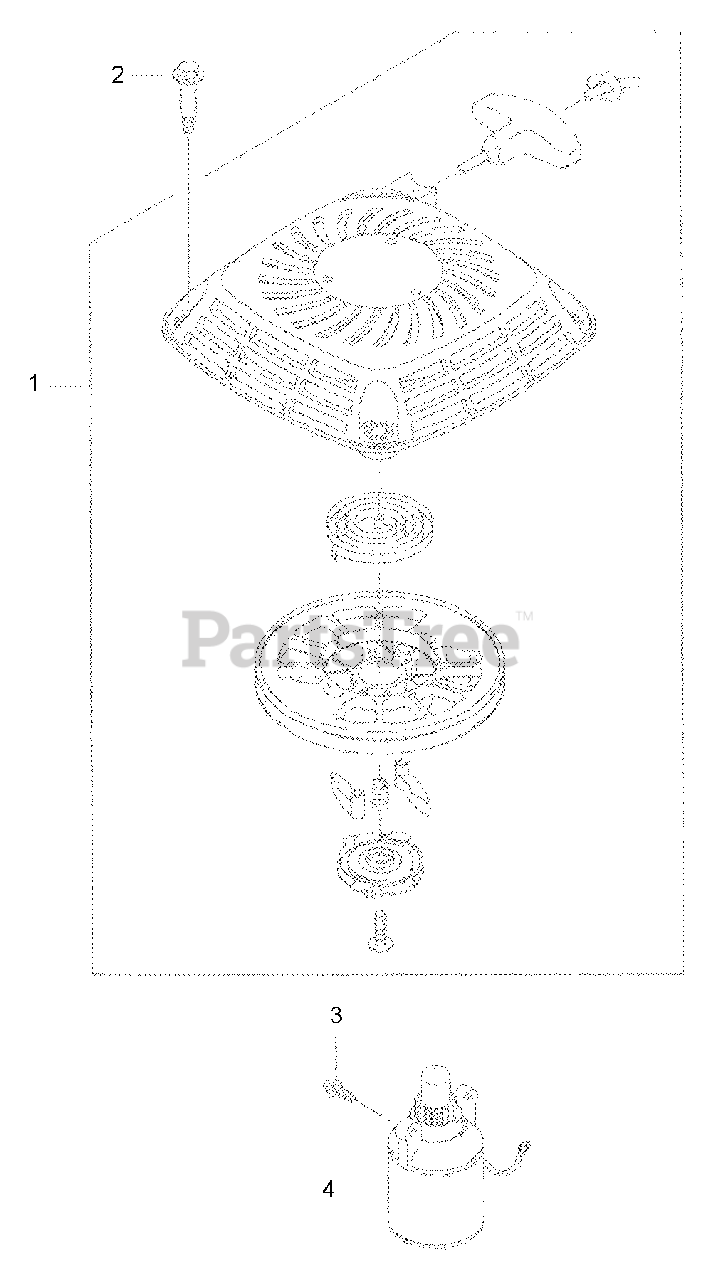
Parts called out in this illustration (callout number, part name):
1	Recoil Starter
2	Bolt, M6
3	Flanged Bolt
4	Electric Starter
